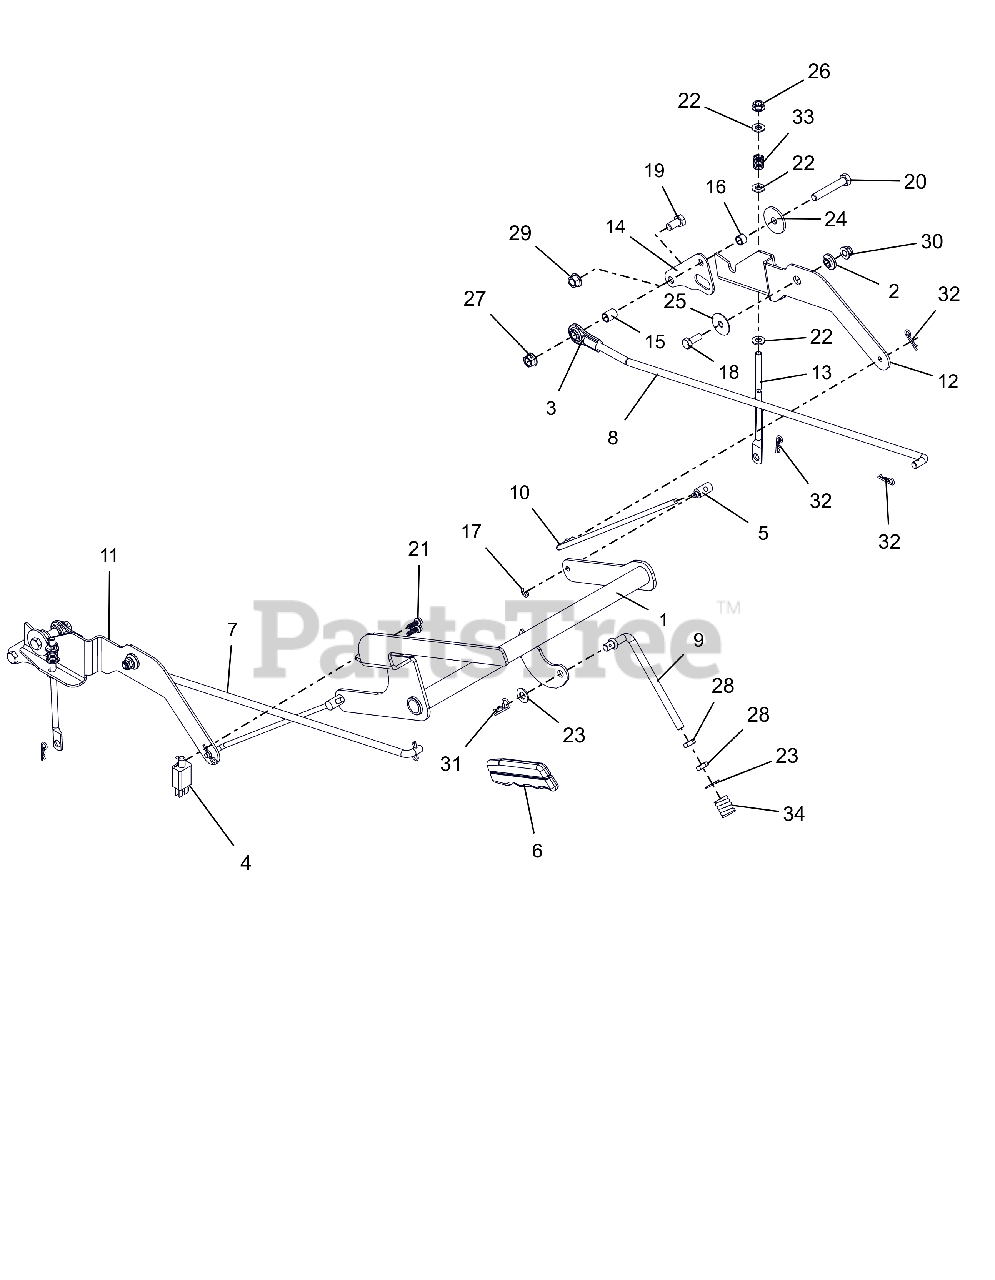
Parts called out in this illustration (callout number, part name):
1	WLDMT, BRAKE LEVER
2	BSHG, FLG .325X.499X.26X.88
3	ROD END, .38 RH
4	SWITCH- DOUBLE POLE N.O./N.O.
5	TRUNION, 1/4-20
6	GRIP, PARKING BRAKE (YELLOW)
7	STEERING, LINKAGE RH
8	STEERING, LINKAGE LH
9	LINK, OVER CENTER, PARKING BRK
10	LINK, BRAKE ARM
11	INTERLOCK, RH BRAKE LINK
12	INTERLOCK, LH BRAKE LINK
13	LINK, BRAKE COG
14	PLATE, TRANSAXLE ADAPTOR
15	SPCR, SLV .385X.500X.652
16	SPCR, SLV .385X.500X.350
17	RG-RTNG-EXT .250X.025
18	BOLT-HEX.31-18X.875 YWZC GR5
19	@BLT-HEX .38-16X.75 GR5 YWZC
20	@BLT-HEX .38-16X2.25 GR5 YWZC
21	SCR-TAP #12X.75 BOSS INDHXHD
22	@WSHR-FL-STL.344X.688X.065YWZC
23	@WSHR-FL-STL.406X.812X.065 YWZ
24	WSHR-FL-STL .380X1.50X.125YWZC
25	WSHR-FL-STL .347X1.254X.048YWZ
26	@NUT-LK-CTR-FLG .31-18 YZ GR F
27	NUT-LK-CTR-FLG .38-16 YWZC
28	NUT-HEX-JAM .375-16 YWZC
29	@NUT-LK-TOP-FLG .38-16 YWZC
30	@NUT-LK-NYL-FLG .31-18 YWZC
31	PIN-HAIR CTR .09 X 1.50 YWZC
32	PIN-HAIR INT .08X.18X1.18 YWZC
33	SPRING, COMPRESSION
34	SG-COMP .187X.56X1.62
